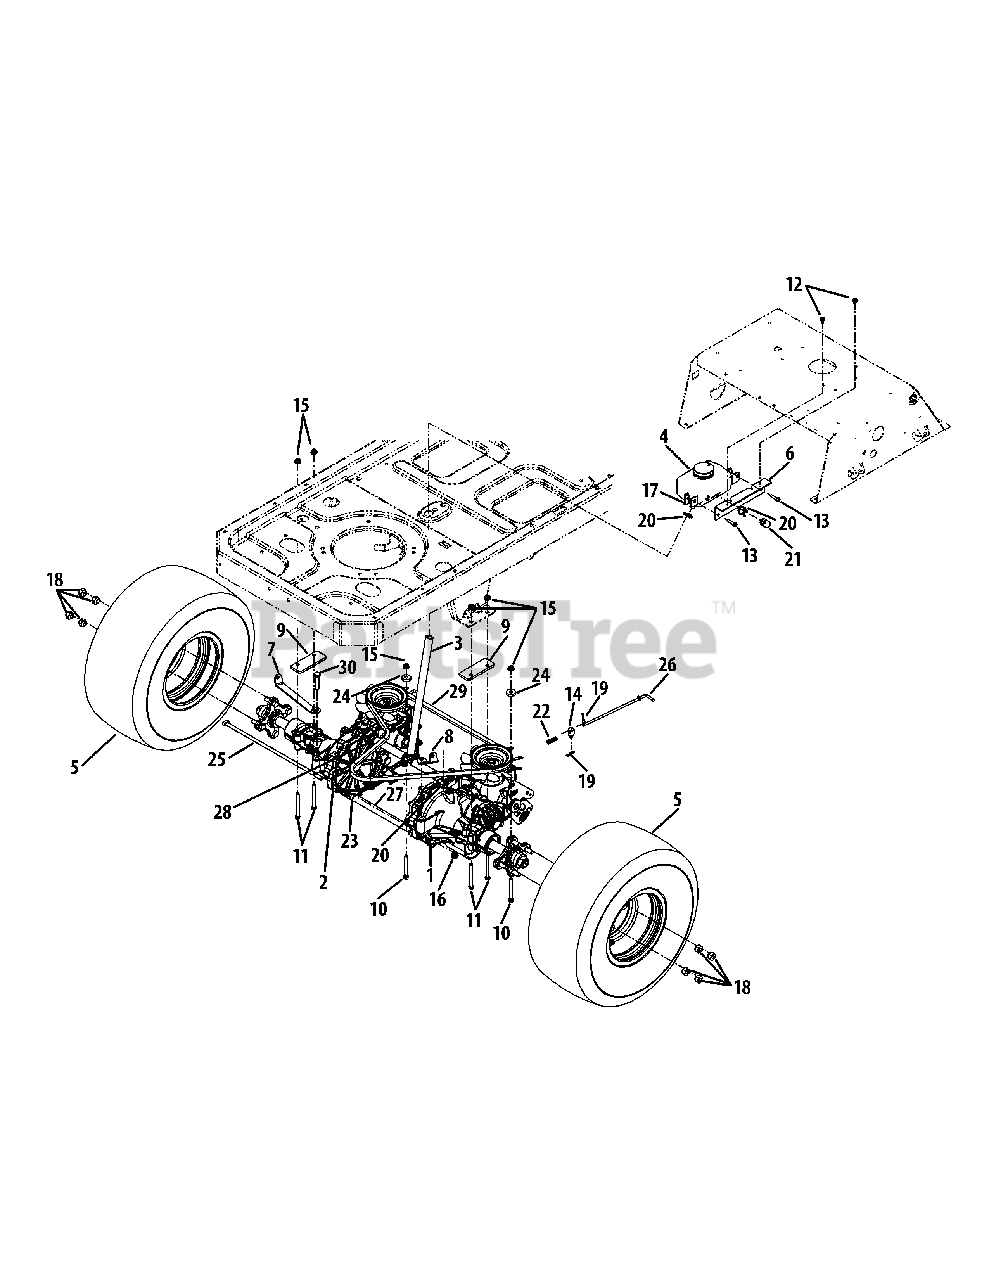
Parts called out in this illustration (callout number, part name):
1	Transmission Assembly (RH)
2	Transmission Assembly (LH)
3	Breather
4	Expansion Tank Assembly
5	Wheel Assembly, 20 x 10 x 8
6	Expansion Tank Bracket
7	Transmission Brace (LH)
8	Transmission Brace (RH)
9	Transmission Spacer
10	Hex Screw, 5/16-18 x 2.75
11	Hex Screw, 5/16-18 x 3.00
12	Screw, 1/4-20 x .500
13	Screw, 1/4-20 x 1.000
14	Ferrule, .325 x .312
15	Flange Lock Nut, 5/16-18
16	Flange Lock Nut, 3/8-16
17	Speed Nut, 1/4-20
18	Lug Nut, 7/16-14
19	Bow-Tie Cotter Pin
20	Hose Clamp, 1/2
21	Cap, 1/2 x .870
22	Compression Spring, .405 x 1.17
23	Extension Spring, .545 x 4.555
24	Flat Washer, .35 x 1.0 x .2
25	Rod, .337 x 14.75
26	Bypass Rod
27	Tube, 7/16 x 3/4 x 11.3
28	Straight Fitting, 9/16 x 1/2
29	V-Type Belt
30	Hex Screw, 5/16-18 x 2.25
